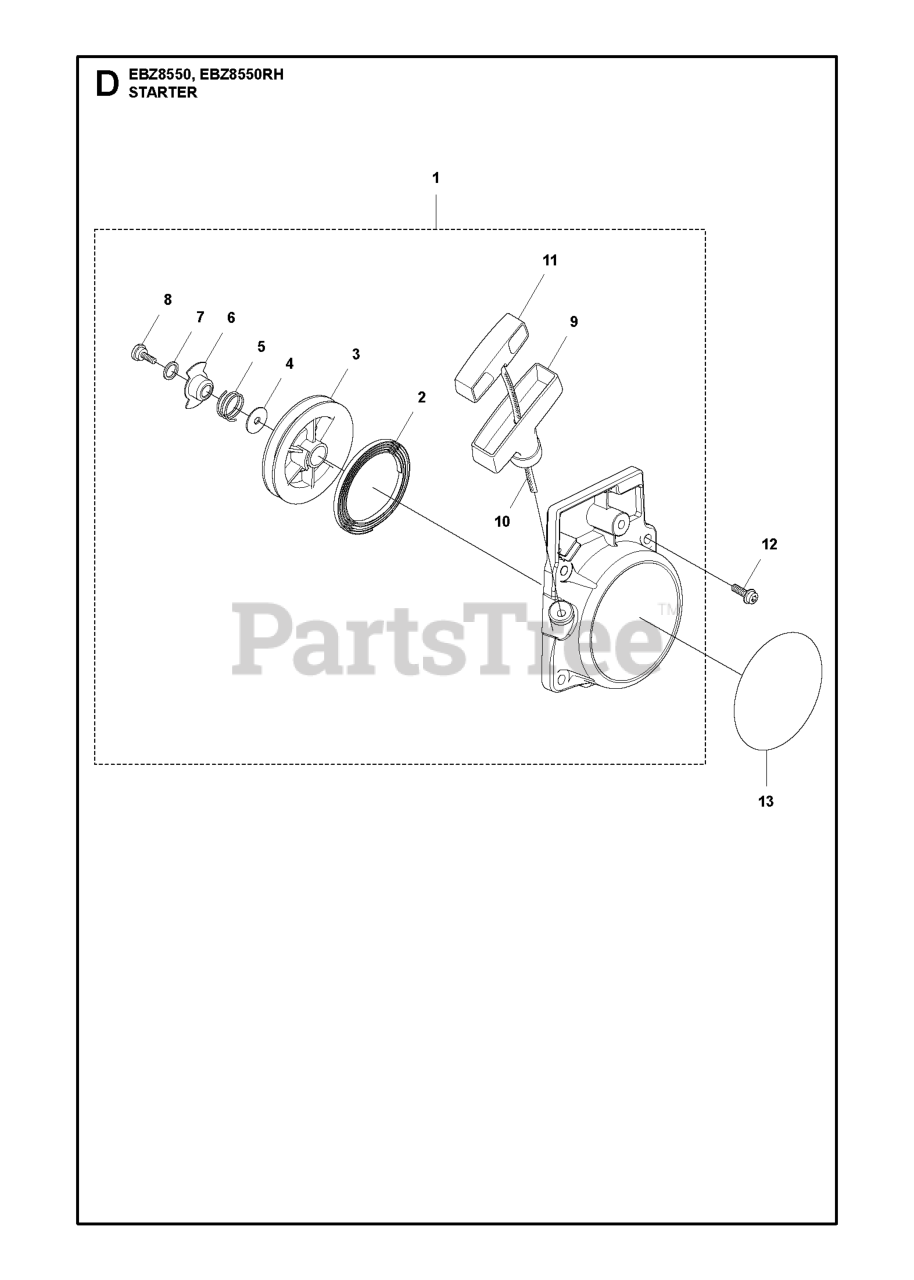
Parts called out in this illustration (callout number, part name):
1	RECOIL ASSY
4	WASHER
5	SPRING FRICTION
6	PLATE
9	KNOB
11	COVER
13	DECAL RECOIL
